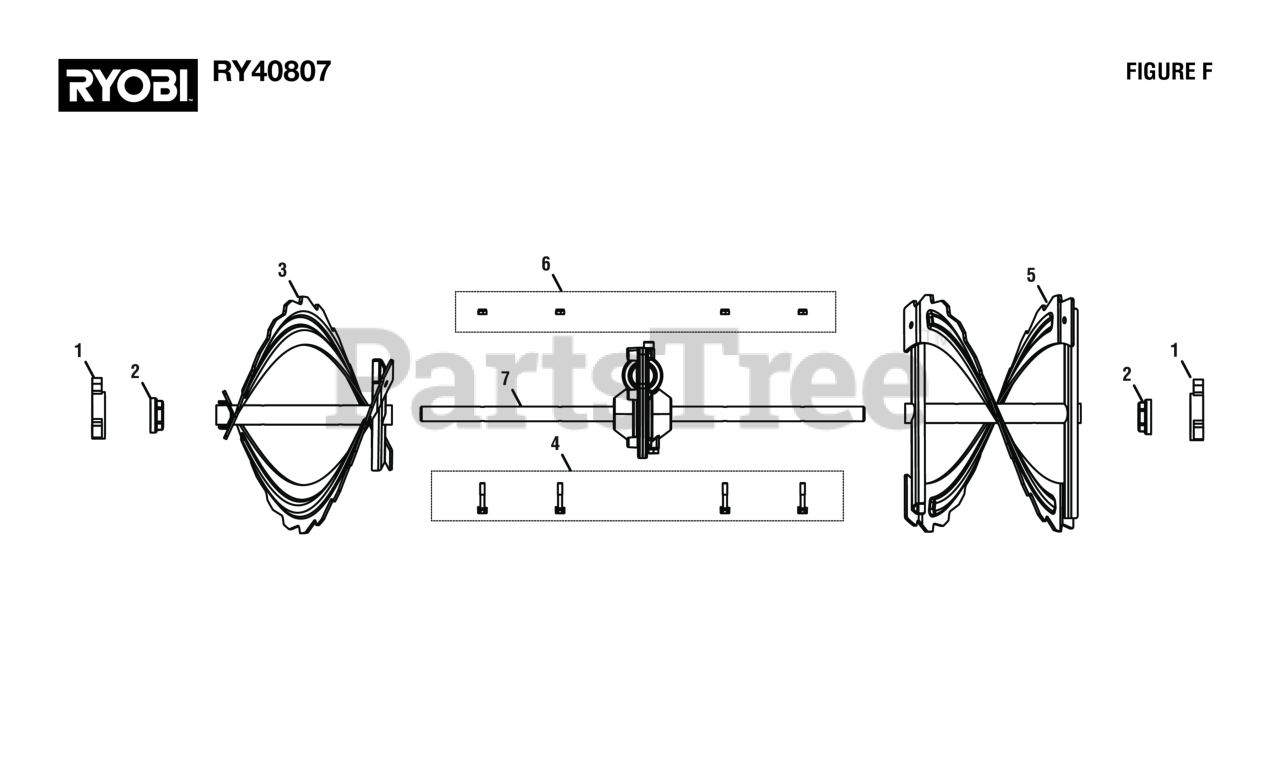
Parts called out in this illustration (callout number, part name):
1	Auger Bearing Retainer Plate
2	Auger Bushing
3	Auger Blade (Right)
4	Screw with Spring Washer (M6 x 35 mm)
5	Auger Blade (Left)
6	Lock Nut (M6 x 6 mm)
7	Attached Auger Worm Gearbox Assembly
